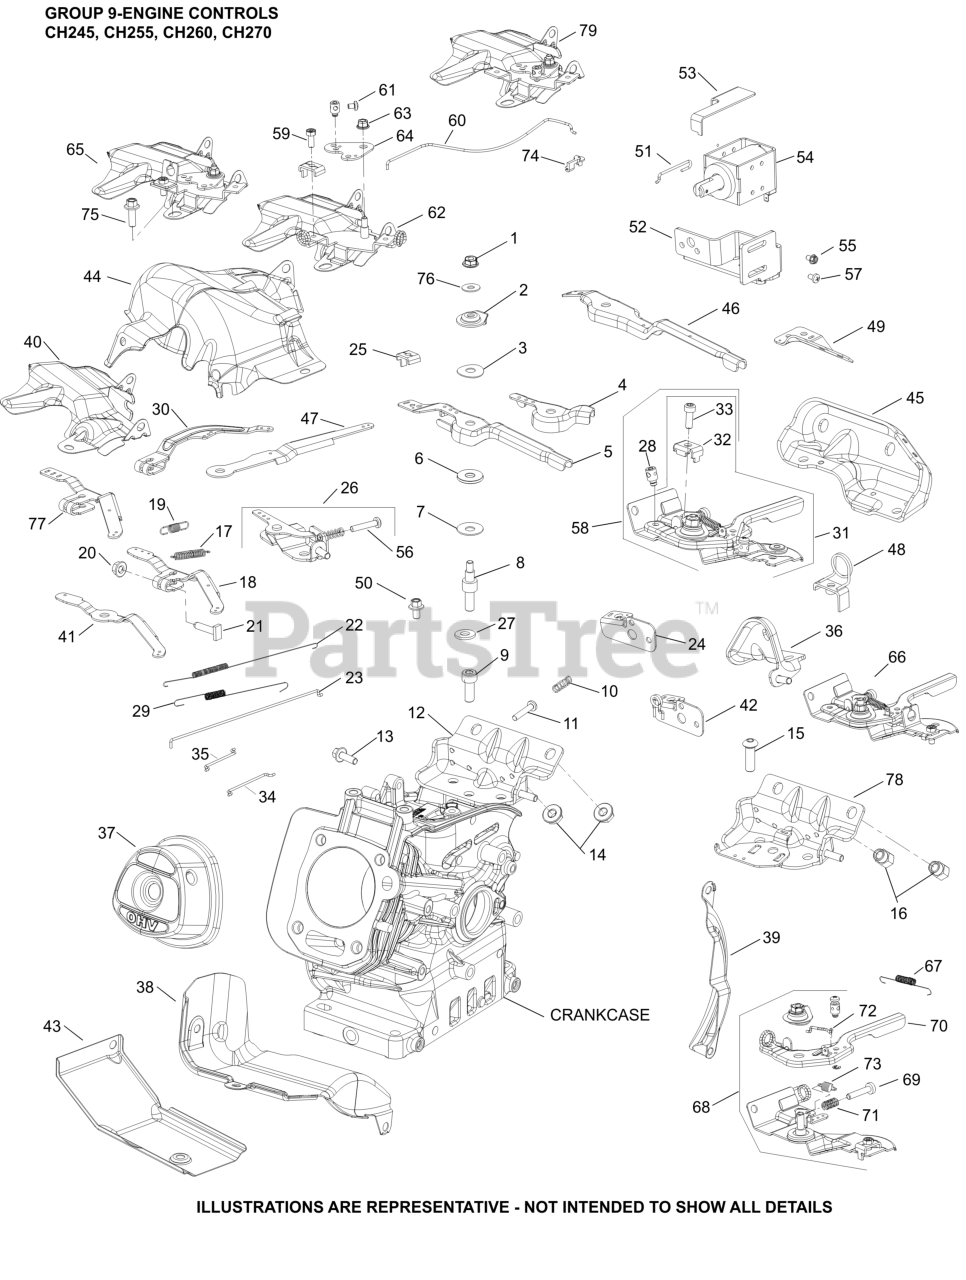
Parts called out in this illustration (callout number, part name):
1	NUT, HEX FLANGE LOCK (M6)
2	WASHER, CONTROL LEVER
3	WASHER, SPRING
5	LEVER, CONTROL (THROTTLE)
6	WASHER, NYLON CONTROL LEVER
7	WASHER, FLAT
8	STUD, CONTROL LEVER
10	SPRING, COMPRESSION
11	SCREW, SPEED ADJUSTING
12	BRACKET, FUEL AND CONTROLS
14	NUT, FLG M8X1.25
18	KIT, GOVERNOR LEVER
19	SPRING, GOVERNOR
21	SCREW, RECTANGLE HEAD (M6)
22	SPRING, LINKAGE
23	LINKAGE, GOVERNOR
24	BRACKET, CABLE CLAMP
25	CLAMP, CABLE
28	KIT, CABLE CLAMP
